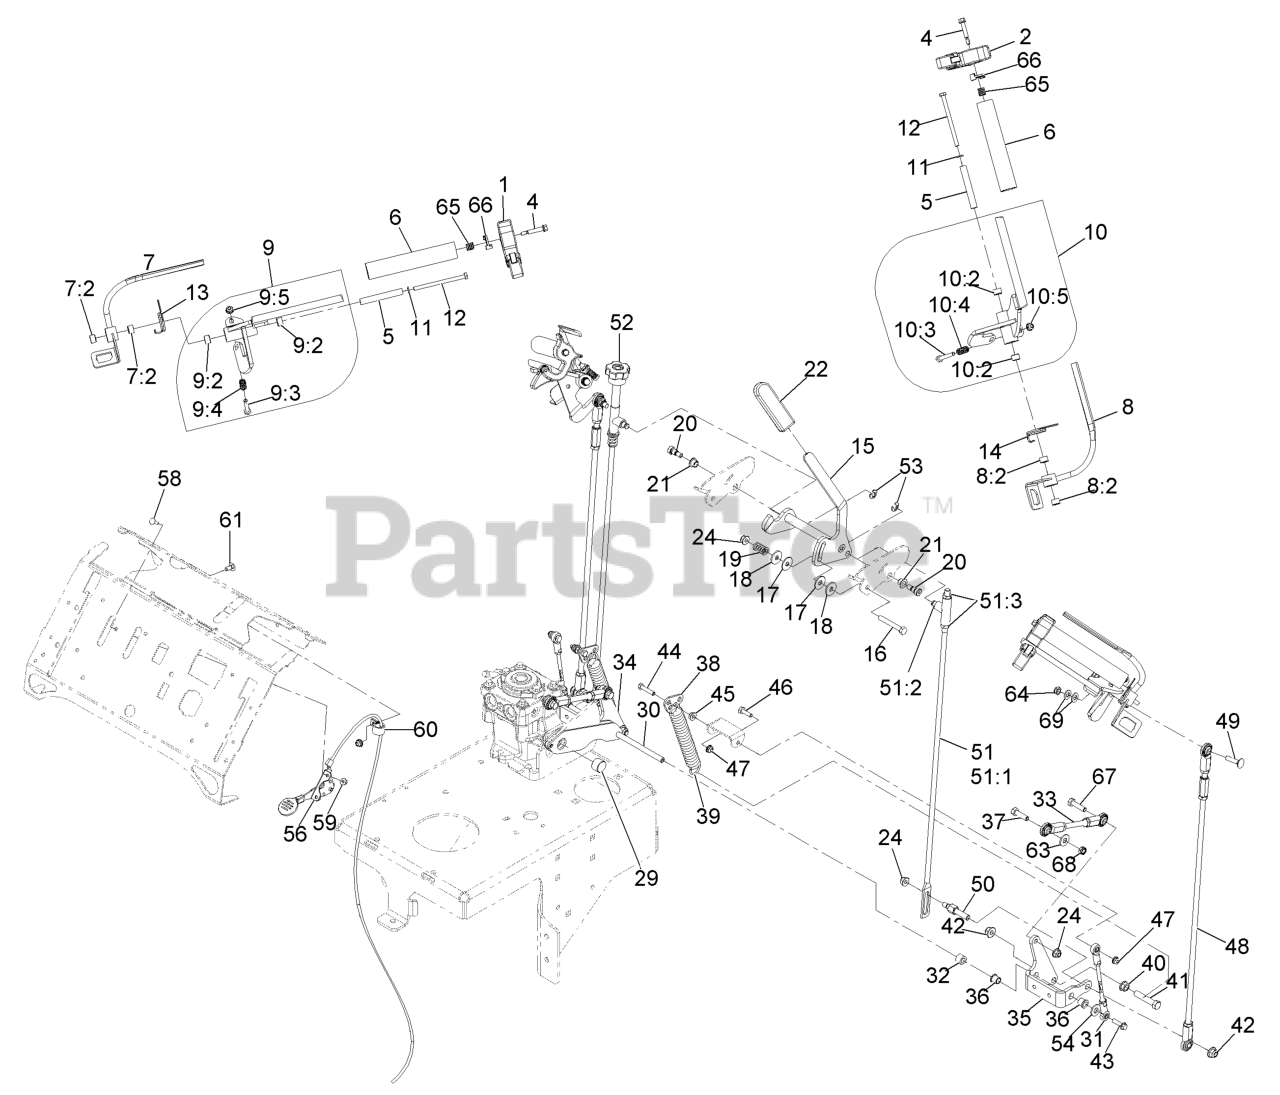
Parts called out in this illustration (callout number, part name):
1	ASM,LATCH RH THUMB
2	ASM,LATCH LH THUMB
4	SCREW-SHOULDER
6	GRIP-BAR, HANDLE
7	OPC-W/BUSHING, RH
7:2	BUSHING-SLEEVE
8	OPC-W/BUSHING, LH
8:2	BUSHING-SLEEVE
9	ASM, RT DRIVE LEVER
9:2	BUSHING-SLEEVE
9:3	SCREW-HH
9:4	SPRING, COMPRESSION
10	ASM, LT DRIVE LEVER
10:2	BUSHING-SLEEVE
10:3	SCREW-HH
10:4	SPRING, COMPRESSION
11	SCREW-HH
12	SCREW-HH
13	SPRING, TORSION
14	SPRING, TORSION
15	SPEED CONTROL ASM
16	SCREW-HH
17	WASHER-FRICTION
18	WASHER-FRICTION
19	SPRING-COMPRESSION
20	SCREW-HSH
21	BUSHING
22	GRIP-HANDLE, STEERING
24	NUT-HF, NI
29	PIN-BELLCRANK LINK RETAIN
30	BELLCRANK LINK ASM
31	ASM, LINK
32	SPACER-WHEEL
33	ASM, MOTION LINK
34	BELLCRANK-LOWER, RT
35	BELLCRANK-LOWER, LT
36	BEARING
37	SCREW-HH
38	LINK, ADJUSTABLE
39	SPRING-EXTENSION
40	NUT-HHF, WHIZ
41	SCREW-HH
42	NUT-HF, NI
43	SCREW-HHF
44	SCREW-HH
46	SCREW-HH
48	ASM, MOTION LINK
49	Bolt-Carriage 5/16-18 X 1 1/4
50	STUD-CONTROL, SPEED
51	ASM, ROD LEFT
51:1	ROD, LEFT
51:3	NUT-HJ
52	ASM, ROD RIGHT
53	RING-RETAINING
54	WASHER-FRICTION
56	CONTROL-THROTTLE
58	BOLT-CARR
59	NUT-LOCK, FLANGE
60	CLAMP-CABLE
61	SCREW-CARR
63	WASHER-FLAT
64	NUT-LOCK, NI
65	SPRING-TANK, FUEL
66	LATCH, ECS
67	SCREW-HH
68	Nut-5/16 Nyloc-Thin
69	WASHER-PLAIN
